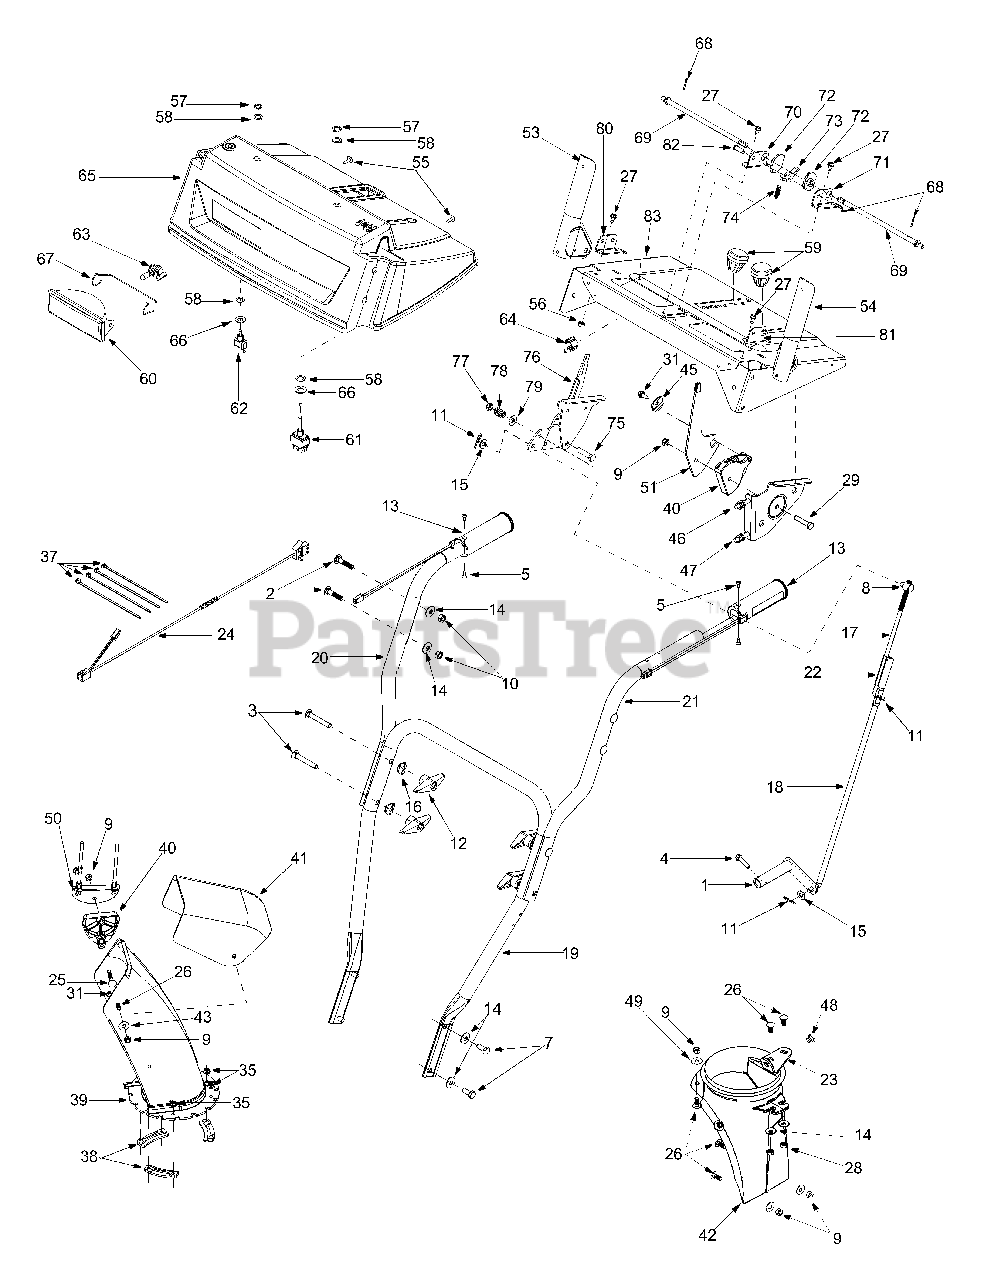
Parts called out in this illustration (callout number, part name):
2	Carriage Bolt 5/16-18 x 1.75"
3	Carriage Bolt 5/16-18 x 2.25"
4	TT Screw 1/4-20 x 1"
5	C-Sunk Screw #10-16x 0.625"
7	Hex Screw 5/16-18 x .75"
8	Ferrule
9	Hex Lock Nut 5/16-18
10	Hex Nut 5/16-18
11	Cotter Pin
12	Handle Knob
13	Heated Grip
14	Belleville Washer
15	Flat Washer
16	Saddle Washer
17	Shift Rod: Upper
18	Shift Rod: Lower
24	Electric Harness: Lower
25	Carriage Bolt: 5/16-18 x 1.5"
26	Carriage Bolt: 5.16-18 x .750"
27	TT Screw: 1/4-20 x 0.5"
28	Hex Nut 5/16-18
29	Hex Screw: 5/16-18 x 1.5"
31	Hex Screw AB:1/4-14 x 0.625"
35	Hex Flange Lock Nut
37	Cable Tie
38	Chute Flange Keeper
39	Lower Chute
40	Cable Guide: Chute Tilt
41	Upper Chute
42	Chute Adapter
43	5/16 Washer
45	Special Washer
46	Control Cable
47	Control Cable
48	Plastic Bushing
49	5/16 Washer
53	Handle Assembly RH
54	Handle Assembly LH
55	Special Hex Screw
56	Hex Sems Nut: 1/4-20
57	Hex Nut
58	Lock Ring: Toggle Switch
59	Shift Knob
60	Lamp Housing
61	Toggle Switch: Double Throw
62	Toggle Switch: Single Switch
63	Halogen Lamp: 50W, 12V
64	Mounting Clamp
65	Handle Panel
66	Flat Washer
67	Headlight Retainer
68	Cotter Pin: 3/32 x .75
69	Cam Rod
72	Cam Handle Lock
73	Handle Lock Pawl
74	Compression Spring: .36 x 1.0
75	Hex Cap Screw: 3/8-24 x 1.5
78	Comp. Spring: .39 x .6 x .88
79	Bell Washer
82	Clevis Pin
